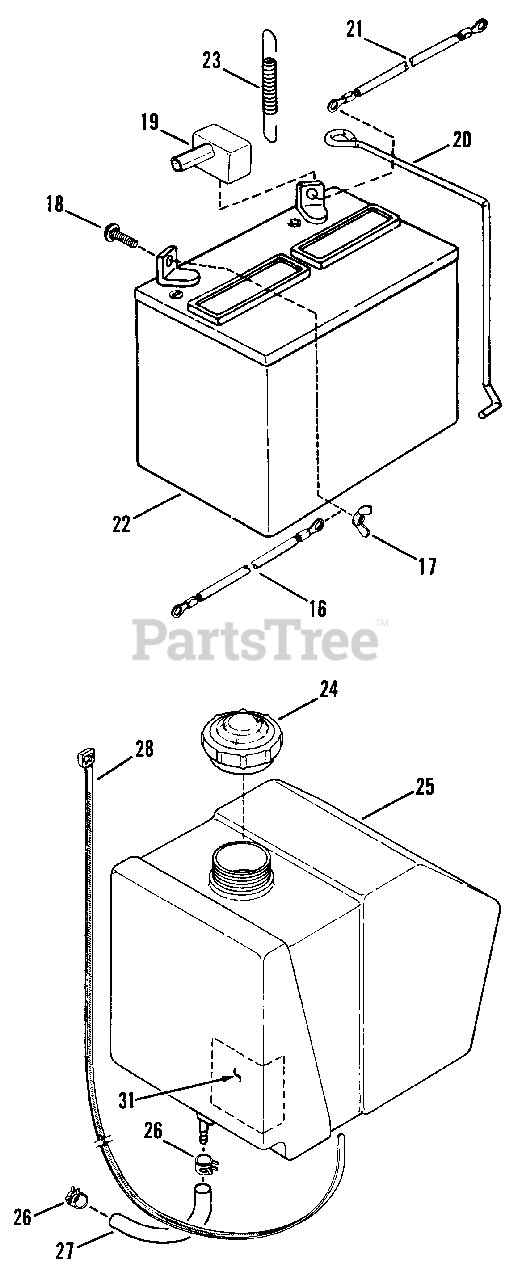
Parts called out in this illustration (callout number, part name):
16	CABLE, Negative Terminal 15" 8 AWG Black
17	WING-NUT, 1/4-20
18	BOLT, 1/4-20 x 3/4" Short Neck Carriage
19	COVER, Positive Terminal
20	CLAMP, Battery
21	CABLE, Positive Terminal 11" 8 AWG Red
22	KIT, Battery, 12 Volt
23	SPRING, Battery Bracket
24	CAP, Fuel Tank
25	TANK, Fuel w/cap
26	CLAMP, Fuel Line .490 x .31
27	LINE, Fuel (14.5" Long) (No longer available)
28	CABLE-TIE, Fuel Tank Hold Down
31	HEAT SHIELD, Fuel Tank 3" x 5.5" (No longer available)
